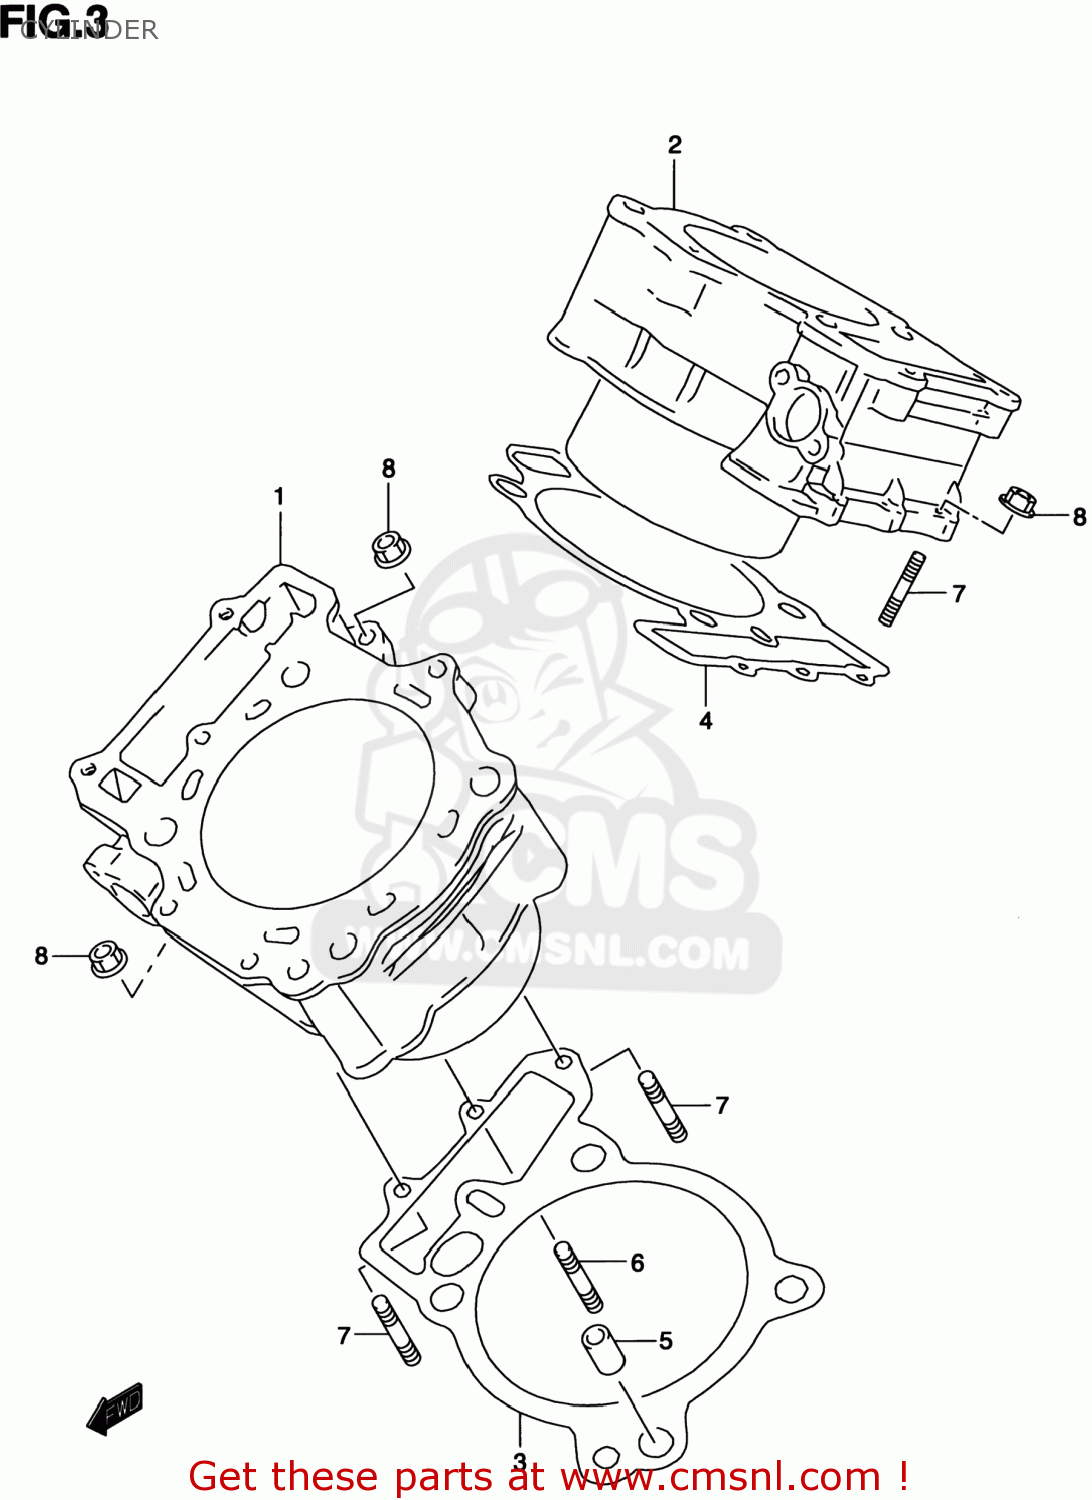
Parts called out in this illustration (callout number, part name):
1	CYLINDER,FRONT
2	CYLINDER,REAR
3	GASKET,CYLINDER FR (NAS)
4	GASKET,CYLINDER RR (NAS)
5	PIN
6	STUD BOLT (L:20)
7	STUD,M6X1X32
8	NUT
